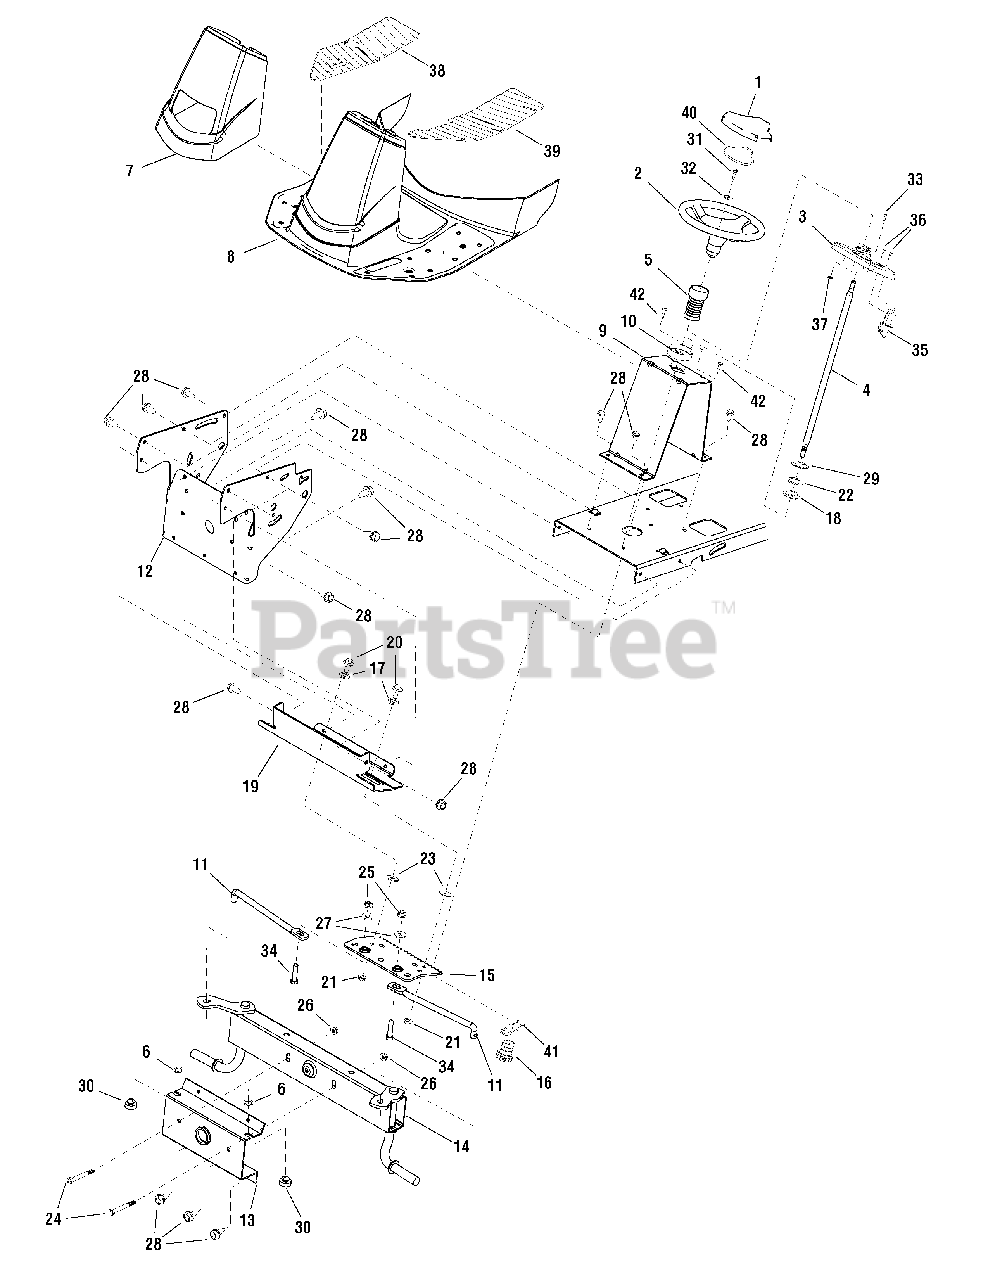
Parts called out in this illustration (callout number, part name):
1	COVER, Steering Wheel
2	STEERING WHEEL
3	DASHBOARD
4	SHAFT, Shaft
5	BELLOWS, Steering
6	WASHER, Flat, .81 x .550
7	FOOTREST SLEEVE
8	FOOTREST, Plastic
9	SUPPORT, Steering
10	BEARING, Upper Steering
11	LINK, Drag
12	BRACKET, Support
13	BRACKET, Axle Front
14	AXLE AND SPINDLE ASSY
15	RACK, Steering
16	GEAR, Pinion
17	ROLLER
18	BEARING, Lower Steering
19	PLATE, Gear Mounting
20	BOLT, Shoulder, .31-18 x 1 1/4
21	NUT, Hex Flange Centerlock 5/16-18
22	WASHER, Flat, 1-1.3 16G
23	WASHER, .328 x 1.062 x .062 Z
24	BOLT, Hex Head, 5/16-24 x 2-3/4, G5
25	NUT, Centerlock 3/8-16
26	NUT, 5/16-24
27	WASHER, Flat, .39-1. 14G
28	CAPSCREW, 5/16-18 x 3/4
29	E-RING, Retainer
30	BUMPER, Rubber
31	SCREW, Self Tapping, 1/4-20 x 3/4
32	WASHER, Flat, .34, 1.20 11G
33	SCREW, Thread Forming, 10-16 x 1
34	BOLT, Hex 3/8-16 x 1-1/2 G5
35	THROTTLE CONTROL
36	SCREW, Self Tap, #8 x 3/8
37	TINNERMAN CLIP
38	FLOORMAT, RH
39	FLOORMAT, LH
40	SUPPORT PLATE, Steering
41	RETAINER, Spring
42	SCREW, Thread Forming, 10-24
